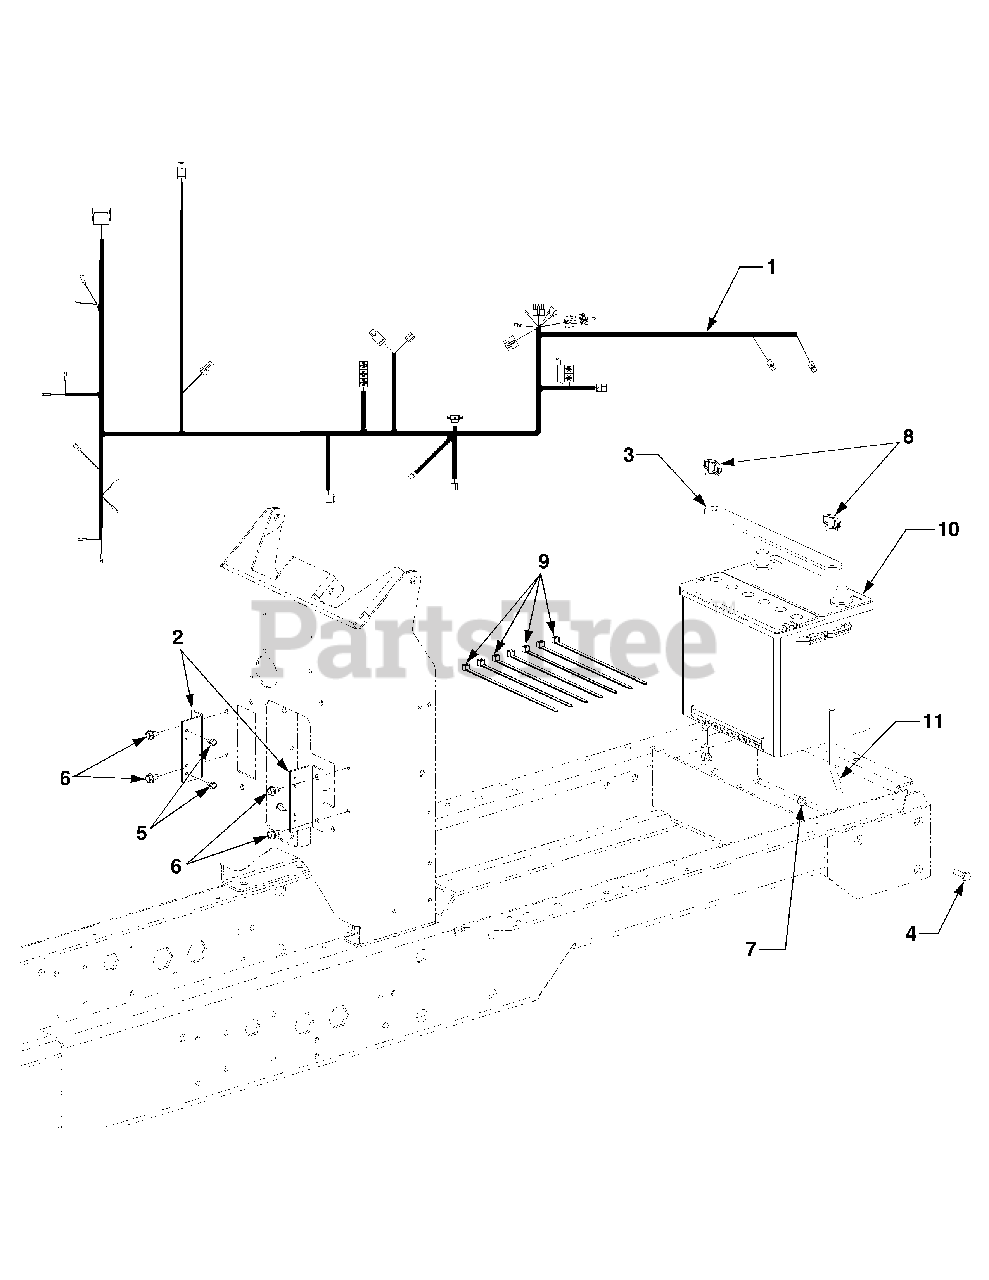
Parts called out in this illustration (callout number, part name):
1	Harness, Main Wire
2	Bracket, Relay Mtg.
3	Strap, Battery Holddown
4	Screw, Hex Cap, 1/4-10 x .875 GR5
5	Screw, Hex Wash Hd. Tapp #10-16 x .5
6	Screw, Hex Wash Hd. Tapp 1/4-20 x .5
7	Nut, Hex Nylon Insert Lock, 1/4-20
8	Nut, Wing w/Bell Washer, 5/16-18
9	Tie, Cable
10	Battery, 500 cca Dry
11	Rod, Battery Holddown
